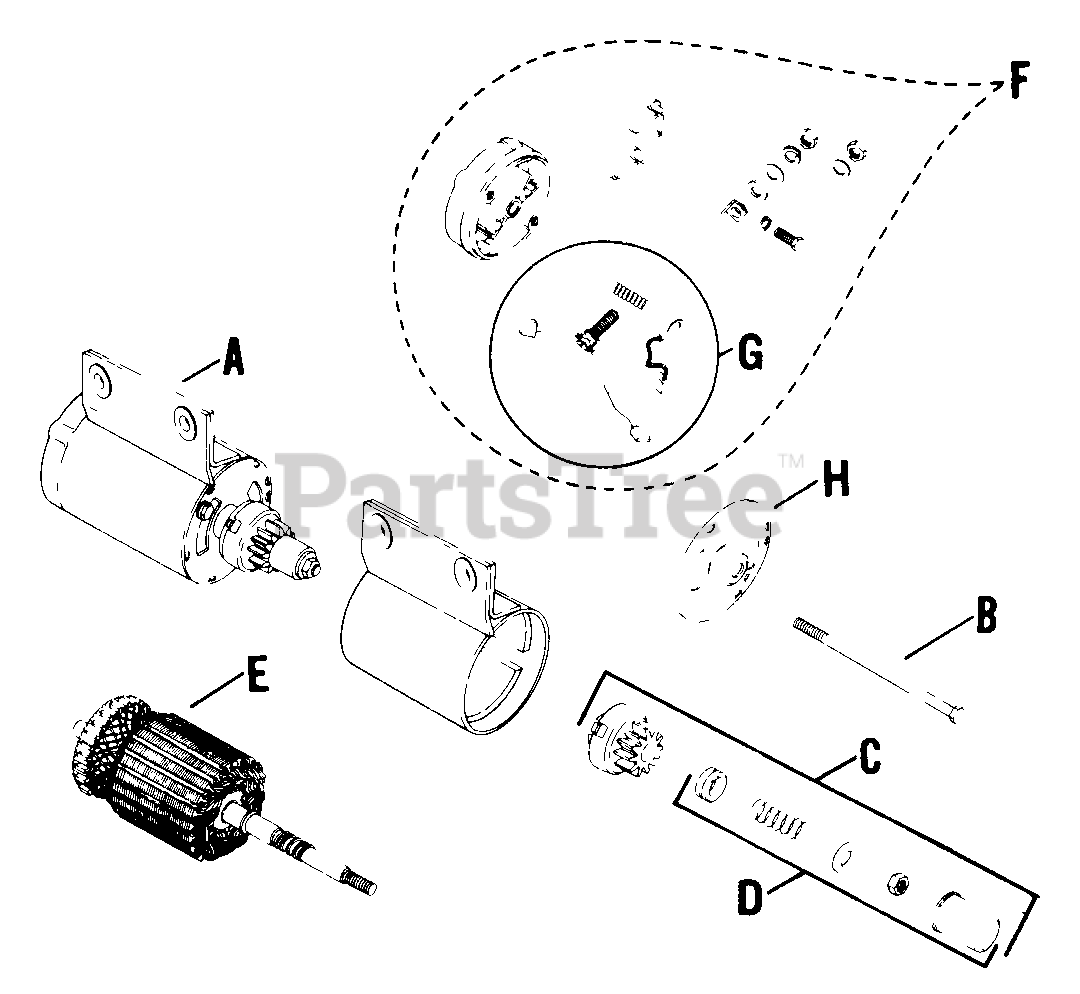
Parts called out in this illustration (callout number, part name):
A	STARTER - USE 41 098 03
A	STARTER - USE 41 098 01
C	KIT - USE 41 755 15
F	CAP - DISCONTINUED
G	KIT - USE 52 755 15
H	CAP - USE 45 081 05
